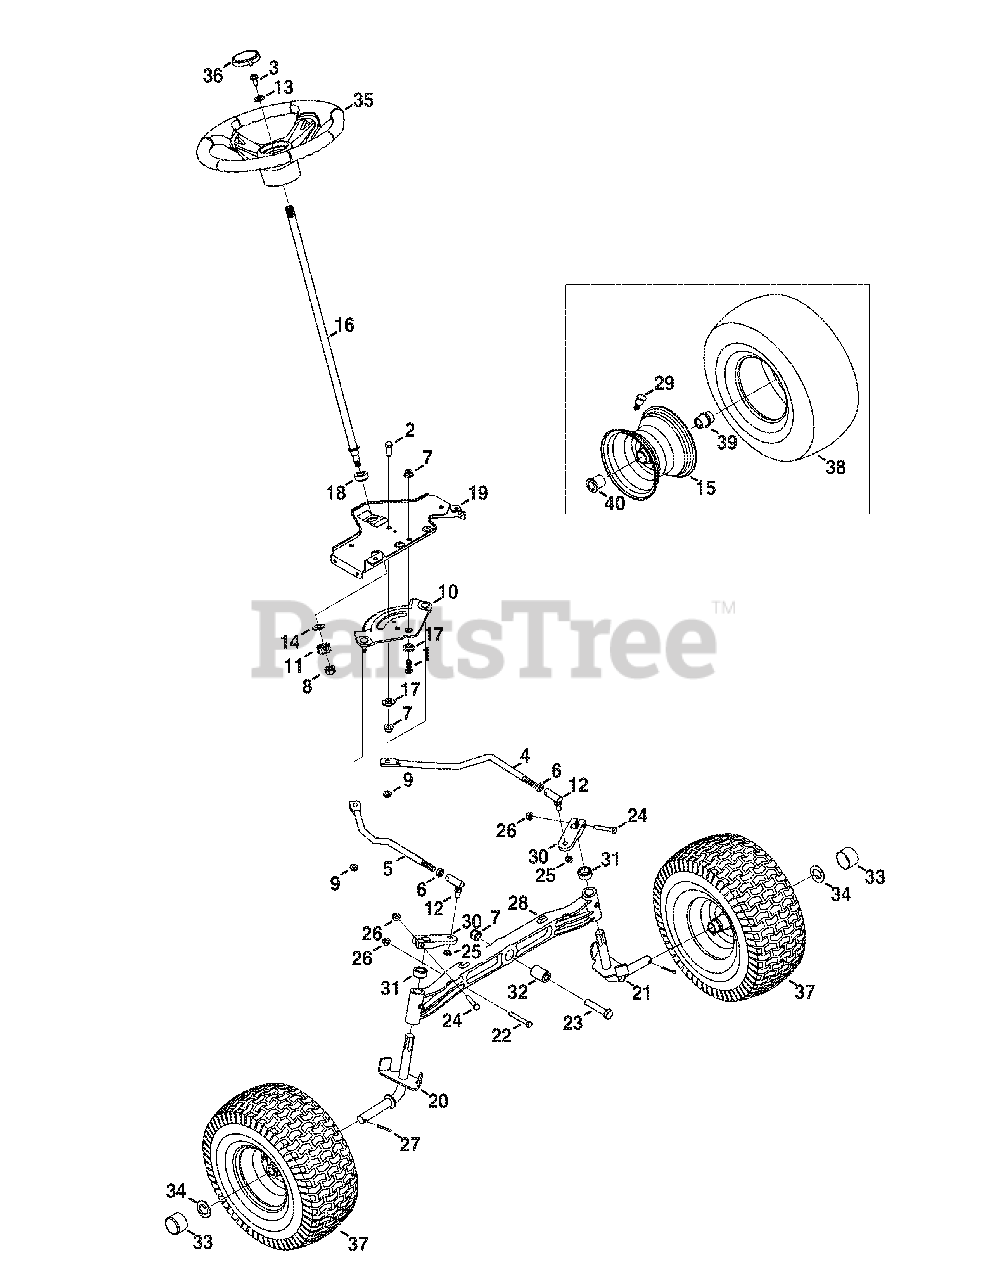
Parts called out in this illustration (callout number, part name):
1	Hex Head Screw, 3/8-16:1.00
2	Hex Head Screw, 3/8-16:1.00
3	Hex Head Screw, 5/16-18:1.00
4	LH Drag Link
5	RH Drag Link
6	Jam Nut, 7/16-20
7	Flangelock Nut, 3/8-16
8	Flangelock Nut, 7/16-20
9	Flangelock Nut, 5/16-18
10	Steering Gear
11	Steering Pinion Gear
12	Ball Joint, 7/16-20
13	Flat Washer, .406 X .875 X .105
14	Flat Washer, .51 X 1.12 X .06:HT
15	Rim Assembly
16	Steering Shaft, .625 OD X 24.25 LG
17	Shoulder Spacer, .385X 1.25 X .3025
18	Hex Flange Bearing 5/8 PM
19	Steering Support Bracket
19	Screw, .750 5/16-18
20	RH Axle Assembly
21	LH Axle Assembly
22	Hex Head Screw, 5/16-18:2.25
23	Hex Head Screw, 3/8-16:2.50
24	Hex Head Screw, 5/16-18:1.75
25	Hexlock Nut, 3/8-24
26	Flangelock Nut, 5/16-18
27	Cotter Pin, 5/32:1.25
28	Pivot Bar Axle
29	Tubeless Air Valve
30	Steering Block
31	Spacer, .71 ID X .125 OD X .56LG
32	Spacer, .385 X 1.00 X 1.5075
33	Bumper Cap
34	Flat Washer, .781ID x 1.590OD
35	Steering Wheel
36	Steering Wheel Cap
37	Wheel Assembly
39	Flange Bearing, .760ID
40	Flange Bearing, .760 x 1.00 x 1.20LG
